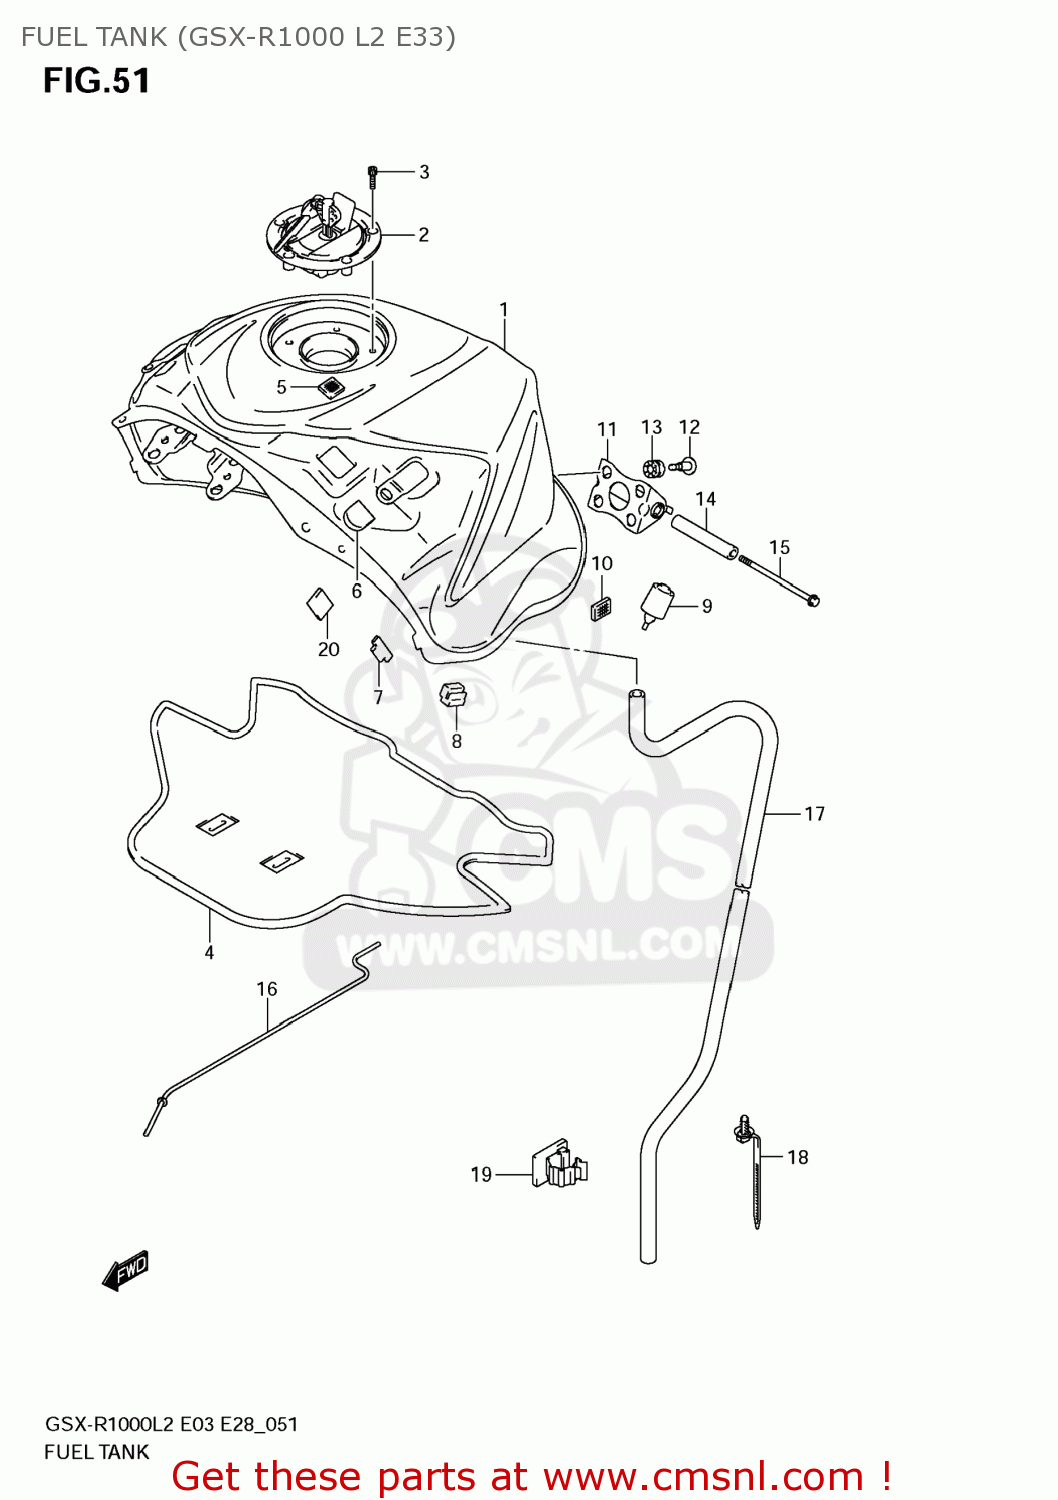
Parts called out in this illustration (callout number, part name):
1	TANK ASSY,FUEL
2	CAP SET,FUEL TANK
3	BOLT(5X20)
4	SHIELD,FUEL TANK HEAT
5	FASTENER
6	CUSHION
7	CUSHION,FUEL TANK COVER
8	CUSHION,FUEL TANK SIDE
9	CUSHION,FUEL TANK RR
10	FASTENER
11	BRACKET,FUEL TANK NO.1
12	SCREW(6X22)
13	CUSHION
14	SPACER,FUEL TANK RR
15	BOLT(6X110)
16	STAY,FUEL TANK
17	HOSE,FUEL TANK WATER DRAIN
18	CLAMP(L:154)
19	CLAMP
20	PAD
